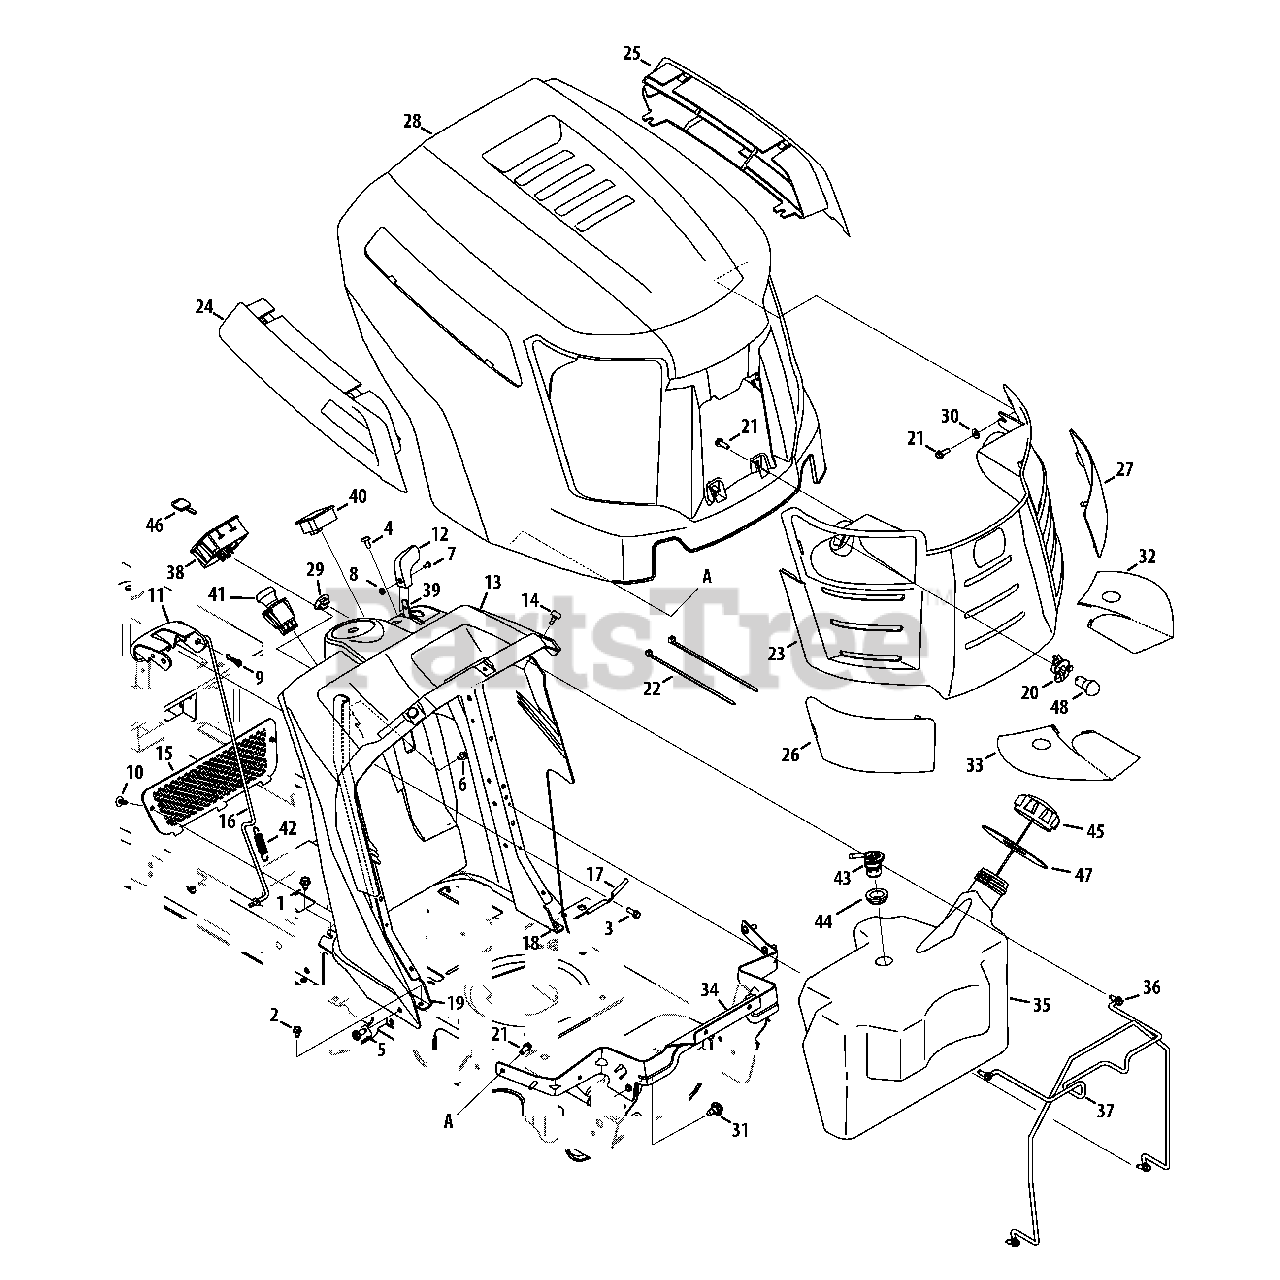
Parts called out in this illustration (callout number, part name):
1	Screw, Self-tapping, 5/16-18, .750
2	Screw, Self-tapping, 1/4-20, 0.500
3	Screw, HL, 1/4-15, 0.750
4	Screw, Ab, 1/4-14, 0.625,
5	Screw, Self-tapping, 5/16-18, 0.750,
6	Screw, Self-tapping, 1/4-20 x .625
7	Screw, Mach, #8-32, 0.375
8	Nut, Hex, #8-32
9	Pin, Cotter, Bow-Tie 72
10	Clip, Ratchet, .250 Dia
11	Lever, Dash, Cruise/Brake
12	Knob, Throttle
13	Dash Panel, A-Style, Man PTO
14	Bumper, .62 Dia X .3
16	Rod, Control, Latch Cub
17	Rod, Lever, Bent
18	Support, Dash, Plate LH
19	Support, Dash, Plate RH
20	Socket, Lamp
21	Screw, 1/4 Dia, .750
22	Tie, Cable, Push Mount 7.5 Lg
23	Grille Ass’y (Incl. 26, 27, 32 & 33)
24	Scoop, Hood, RH A-Style
25	Scoop, Hood, LH A-Style
26	Lens, Hood, RH A-Style
27	Lens, Hood, LH A-Style
28	Hood, A-Style
29	Plug, Choke
30	Washer, Flat, .271, .630, .065
31	Screw, Shoulder, .43x.29, 5/16-18
32	Reflector, Cub A Style, LH
33	Reflector, Cub A Style, RH
34	Bracket, Pivot, Hood A-Style
35	Tank, Fuel, 3.30 Gal.
36	Screw, Self-tapping, 1/4-20, .625
37	Rod, Support, Fuel Tank
38	Module Switch, Ignition
39	Cable, Throttle/Choke, 38"
40	Meter, Indicator
41	Switch, Electric PTO, Yellow
42	Spring, .500 Dia. x 2.733
43	Valve, Rollover Grommet
44	Grommet, Rubber, 23.0 ID
45	Cap, Fuel
46	Key, Assembly
47	Gasket, Fuel Tank
48	Lamp, 12v
